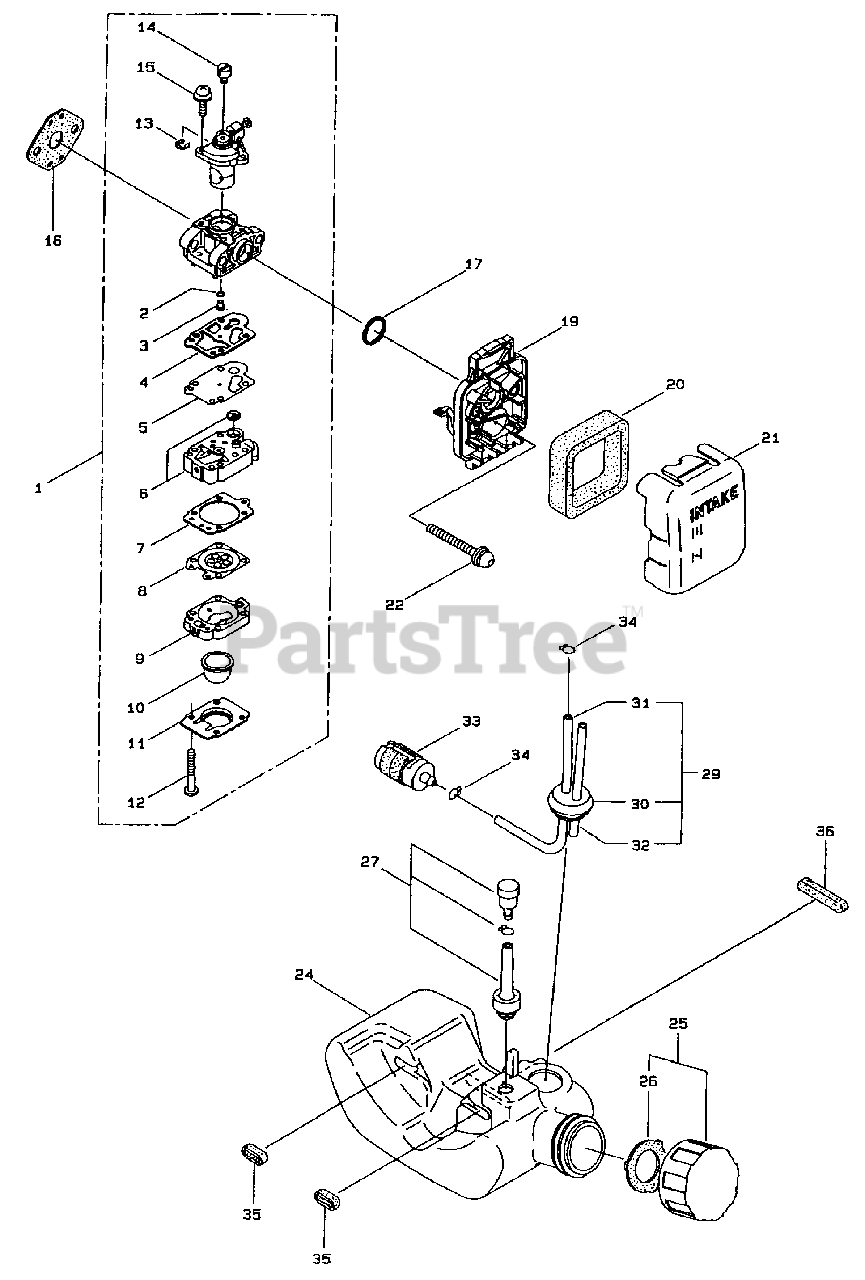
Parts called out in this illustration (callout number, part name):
1	Carburetor Assembly (Incl. Ref. # 2-15)
3	Main Jet
5	Diaphragm
6	Pump Body
8	Diaphragm
9	Purge Body
10	Primer Bulb
11	Cover Plate
22	Cap Screw
24	Fuel Tank
25	Fuel Tank Cap Assembly (Incl. Ref. # 26)
27	Breather Assembly
29	Fuel Pipe Assembly (Incl. Ref. # 30-32)
31	Fuel Pipe
32	Return Pipe
33	Fuel Filter Assembly
